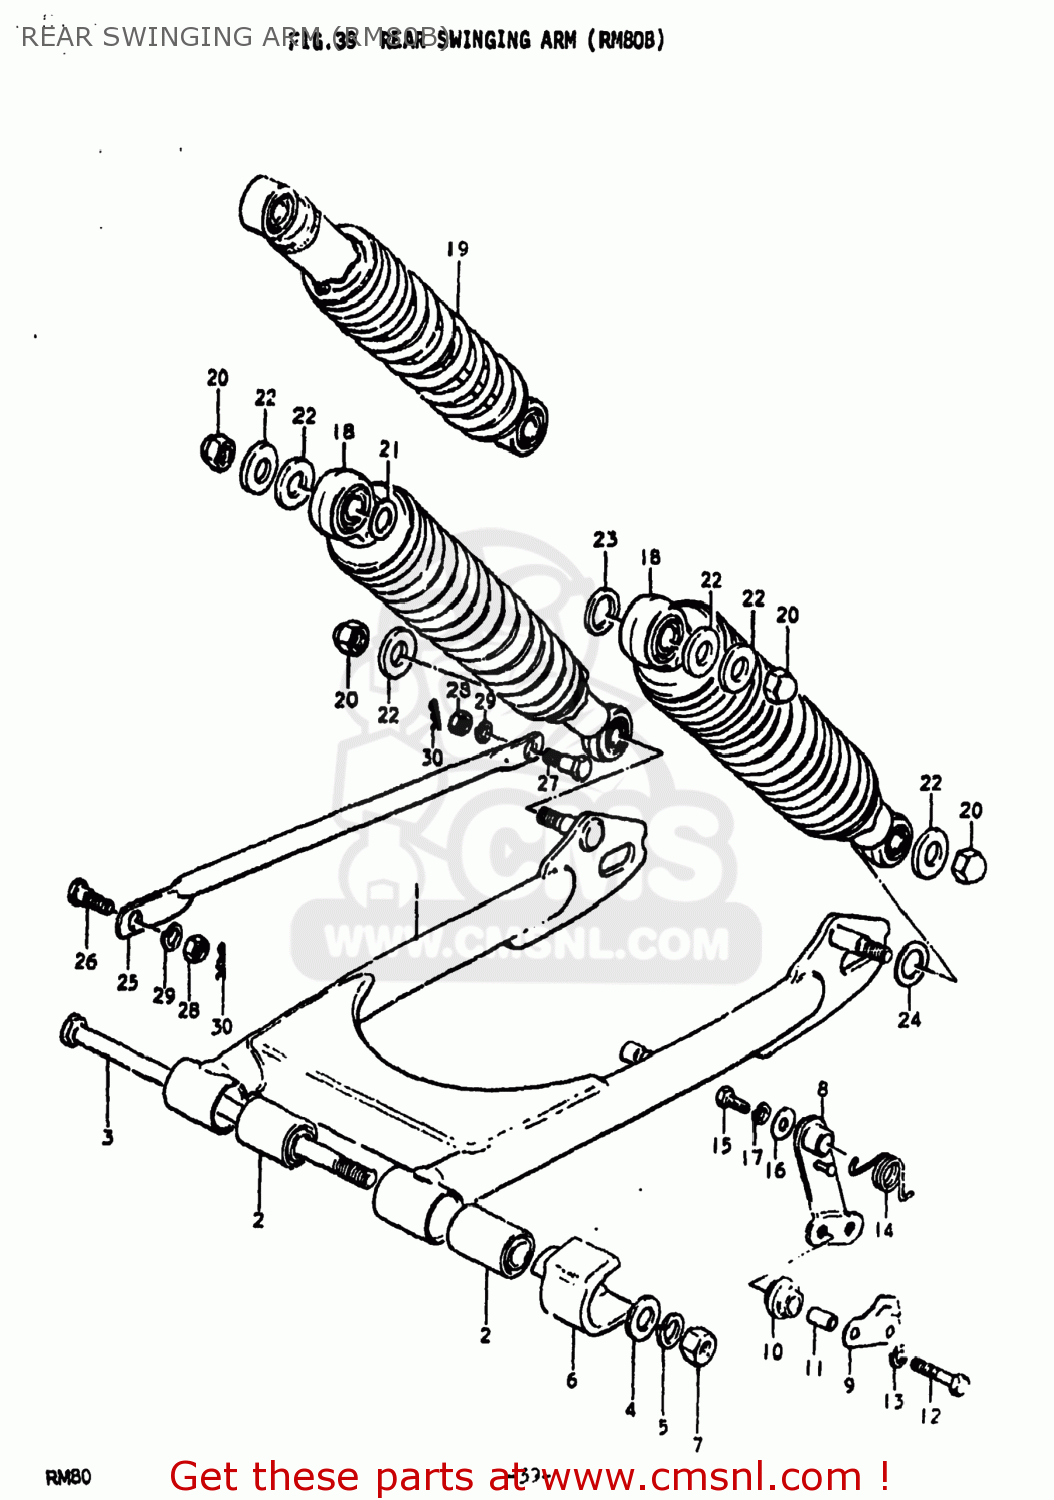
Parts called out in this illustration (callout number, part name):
1	SWING ARM ASSEMBLY,REAR
2	BUSH
3	SHAFT,REAR SWING ARM
4	WASHER
5	LOCK WASHER
6	BUFFER,CHAIN TOUCH DEFLECTOR
7	NUT
8	TENSIONER,CHAIN
9	PLATE,CHAIN TENSIONER
10	RUBBER,CHAIN GUARD
11	SPACER(6.5X10.5X22.5)
12	BOLT
13	LOCK WASHER
14	SPRING
15	BOLT
16	WASHER
17	LOCK WASHER
18	SPRING
19	SPRING
20	NUT, LOWER LH
21	WASHER
22	WASHER
23	WASHER (12.5X24X3.2)
24	WASHER(12.5X20X1)
25	TORQUE LINK,REAR
26	BOLT(8X22)
27	BOLT(8X26.5)
28	NUT
29	LOCK WASHER
30	CLIP
